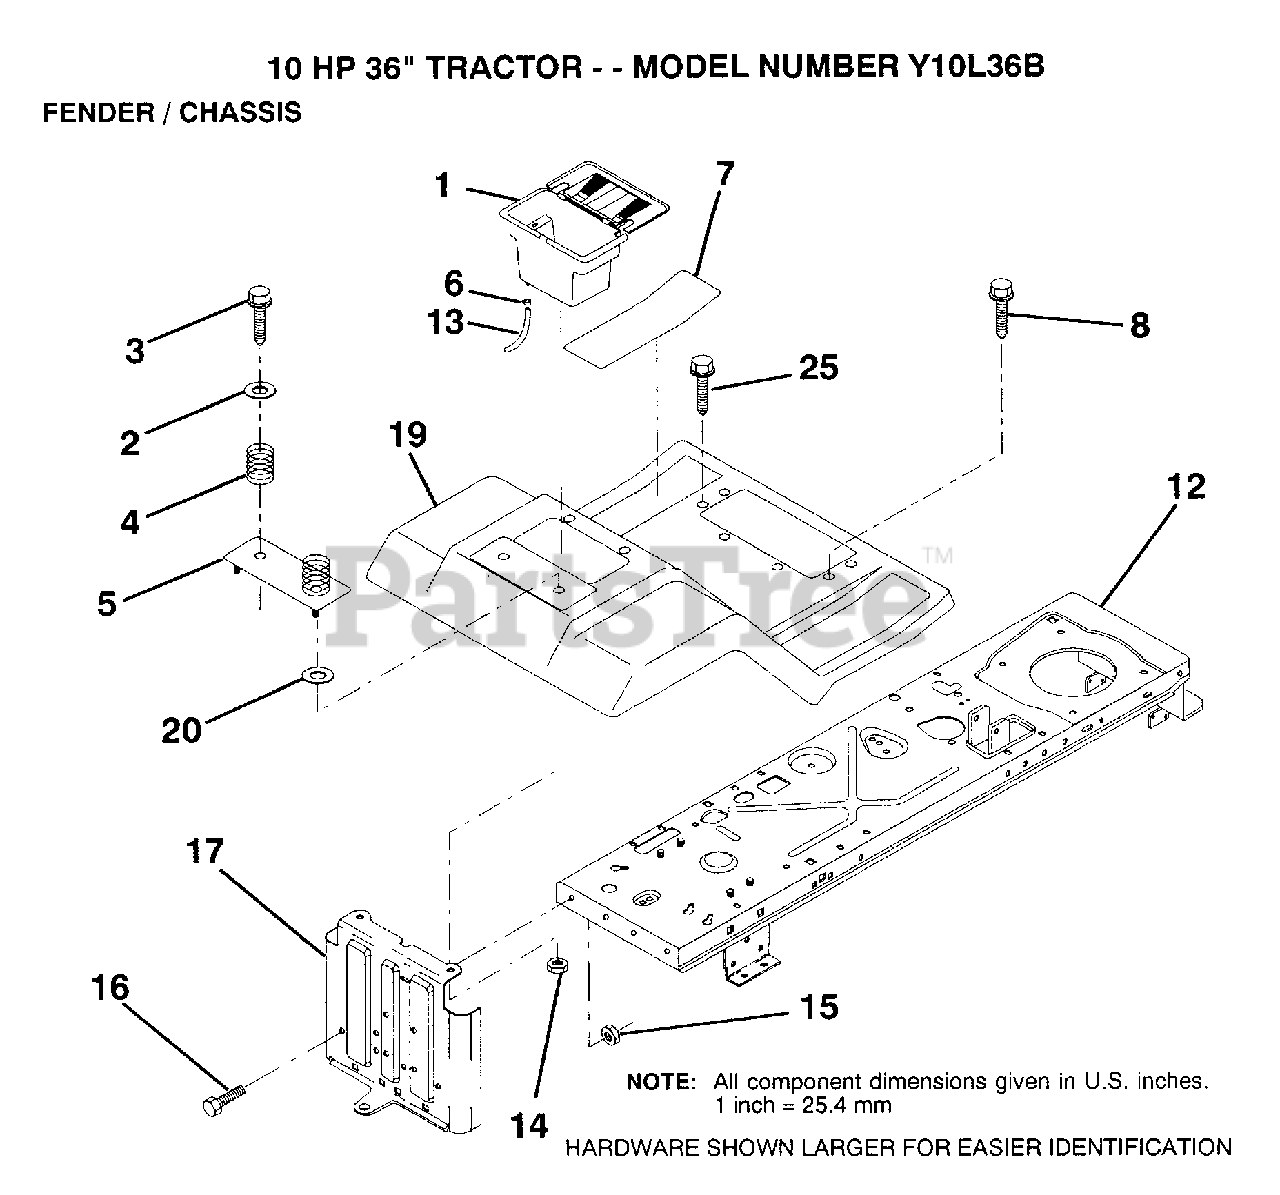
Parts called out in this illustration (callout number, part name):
2	WASHER
3	SCREW
4	SPRING COMPRESSIO
5	BTRY FENDER PLATE
6	HOSE CLAMP T
7	PAD FOOTREST
8	SCREW
13	TUBE T
14	NUT
16	BOLT
17	DRAWBAR
25	SCREW TI
